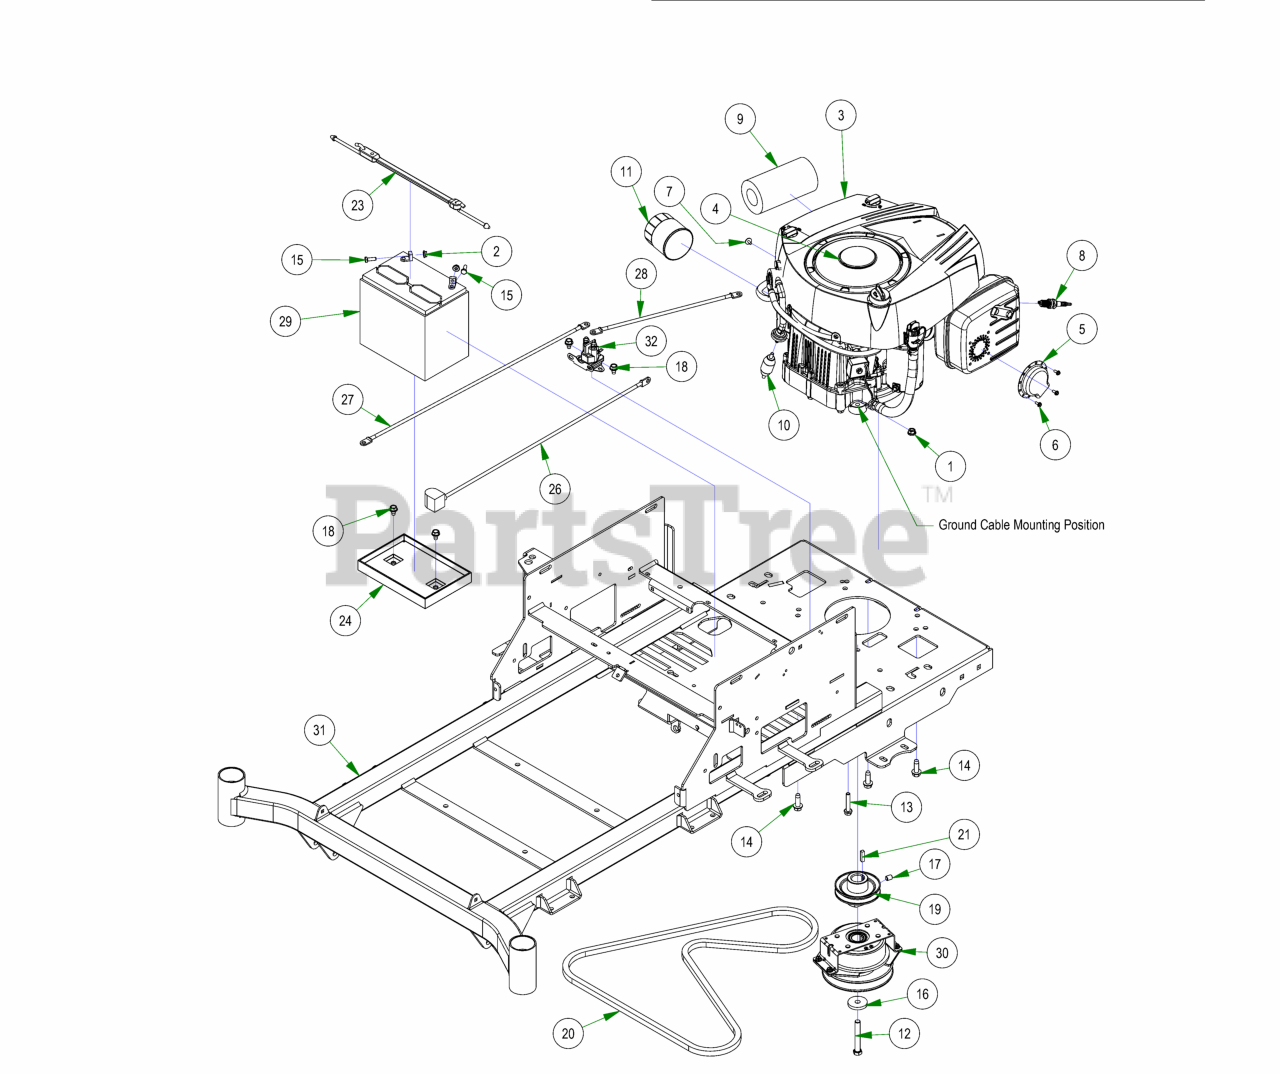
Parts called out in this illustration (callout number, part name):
1	5/16-18 Gr5 Distorted-Thread Flange Locknut
2	1/4-20 HEX SERRATED FLANGE NUT HARD/ZINC
3	19 HP Briggs Engine
4	Briggs 19HP Rotating Screen
5	Muffler Deflector- P/N-222573
6	Muffler Deflector Screws -P/N-96046
7	Choke cable screw/washer- P/N-96073
8	Spark Plug
9	19/21 HP Briggs Air Filter
10	Universal Inline Fuel Filter
11	Oil Filter
12	7/16-20x3” Hex Bolt GR 8 W/ Patch
13	5/16-18x1-3/4 Gr5 Hex Flange Screw Zinc Clear
14	3/8-16 X 1-1/8 HEX WASHER UNSLOT SERRATED (TRI-LOB) TRS ZINC YELLOW
15	1/4-20 X 3/4 HEX CAP SCREW (GR.5) ZINC
16	CLUTCH WASHER
17	3/8-16 X 1/2 SOCKET SET SCREW (CUP PT) PLAIN
18	5/16-18 X 1/2 HWH unslot (F) tcs zinc
19	3-3/4" Motor Pulley
21	1/4 X 1 SQ MACHINERY KEY 1018 STL PLN
22	2023 Battery Hold Down Assembly
23	2023 Rubber Battery Hold Down Strap
24	Battery Tray
26	24 inch Black Cable – MZ/ZT
27	24" Red Battery Cable
28	12 in red battery cable
29	SP-35 Battery
31	2024 MZ 42-48 Frame
